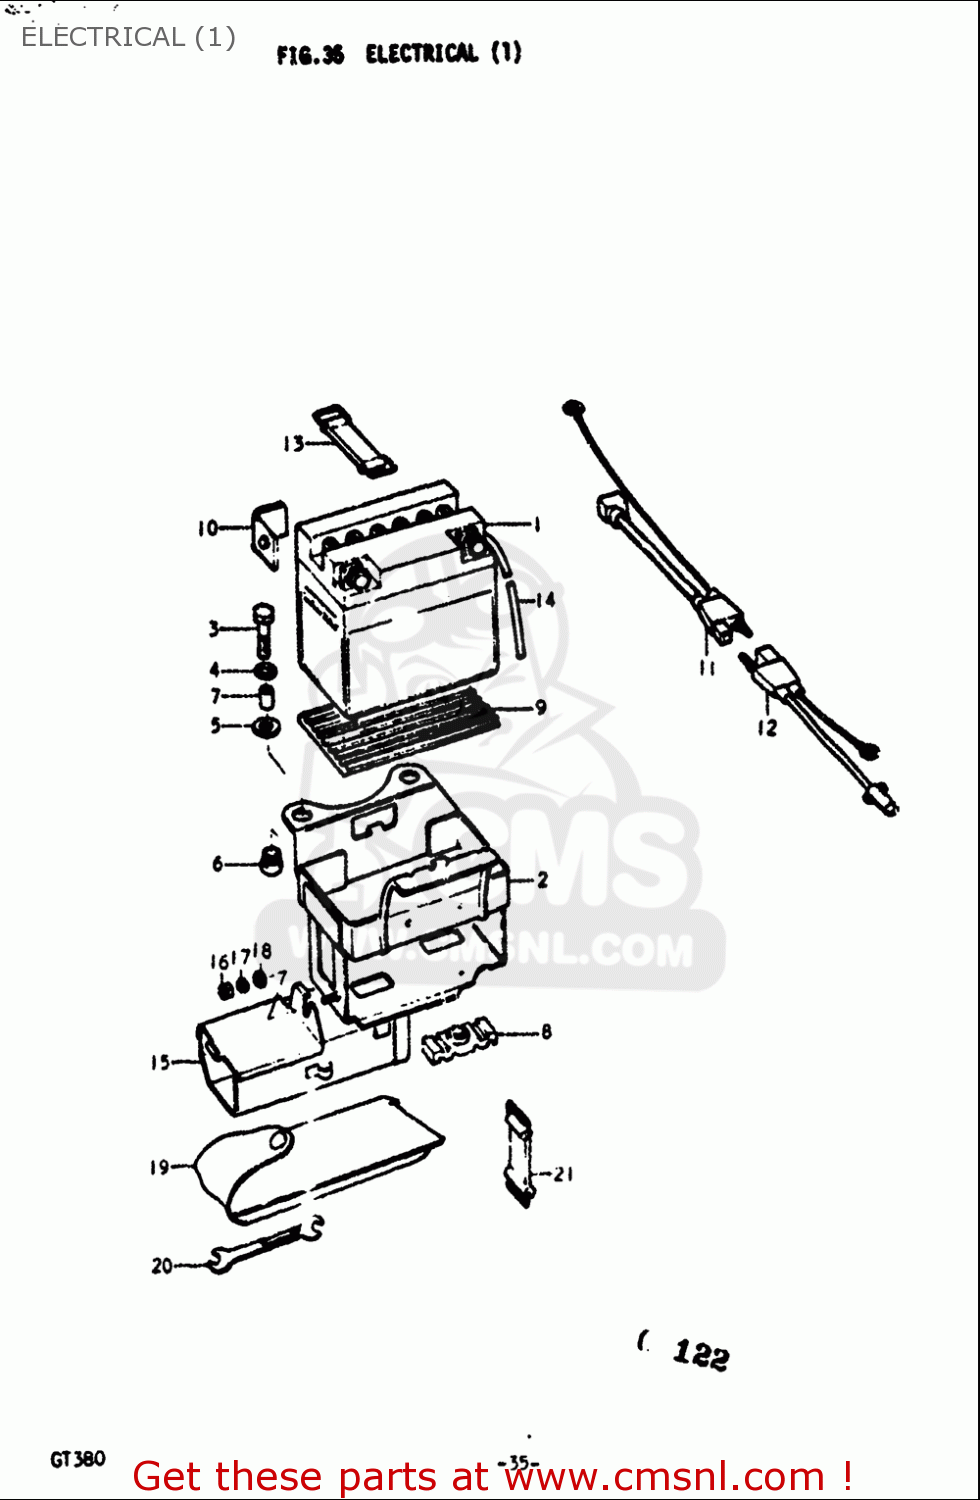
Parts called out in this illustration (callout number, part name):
1	BATTERY ASSY(YB7-A)
3	BOLT
4	WASHER,LOCK
5	WASHER(6.5X18X1.6)
6	CUSHION
7	SPACER(6.1X8X15.5)
9	PROTECTOR,BATTERY
10	PROTECTOR(170X95X3.0)
11	LEAD WIRE
12	WIRE,BATTERY LEAD
13	BAND
14	HOSE,BATTERY EXHAUST(L:780)
16	NUT
17	WASHER,LOCK
18	WASHER
19	TOOL ASSY
21	BAND
